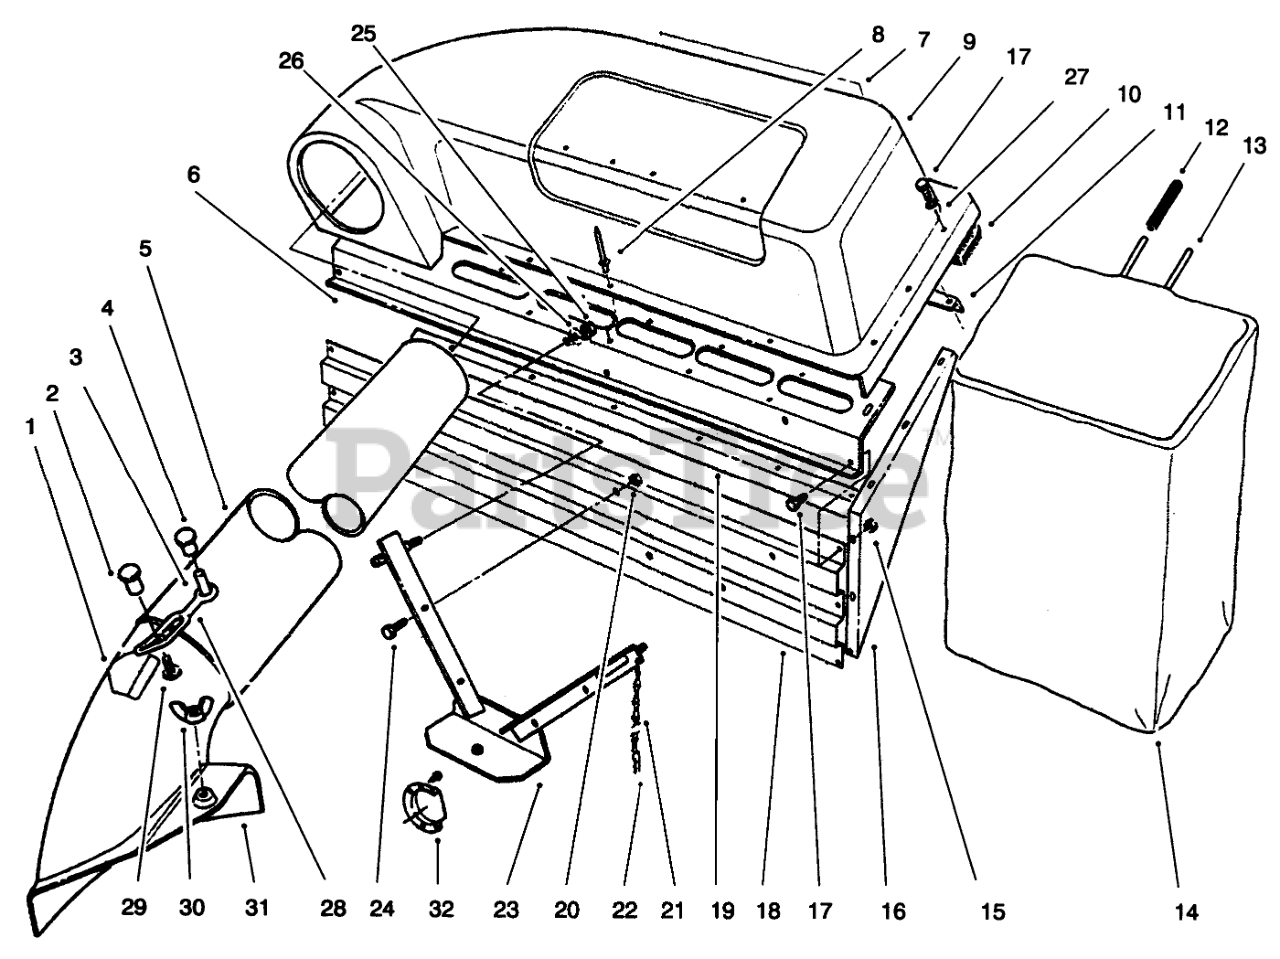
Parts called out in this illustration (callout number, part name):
1	DECAL-DANGER
3	SPACER-INTERLOCK
4	FASTENER-PANEL
6	COVER SUPT BAFFLE B
7	Decal-Twin Bagger
8	RIVET-POP
9	COVER
10	FOAM SEAL
11	BAG FRAME BRKT
12	GRIP-HANDLE, BAG
13	BAG FRAME
15	NUT-LOCK, NI
16	Plate-Side
17	SCREW-HH
18	MUFFLER SHIELD
19	BAG SUPPORT CHANNEL
20	NUT-LOCK, NI
21	6-LINK CHAIN W/HOOK
22	PIN-HAIR
23	V-Bracket
24	SCREW-HH
25	NUT-LOCK, NI
26	WASHER-FLAT
27	WASHER-FLAT
28	RETAINER-DUCT
29	SCREW-HWH
30	NUT-WING SPECL
31	Assembly-Chute (Incl. Ref. #1, 2 & 29)
32	MUFFLER DEFLECTOR
